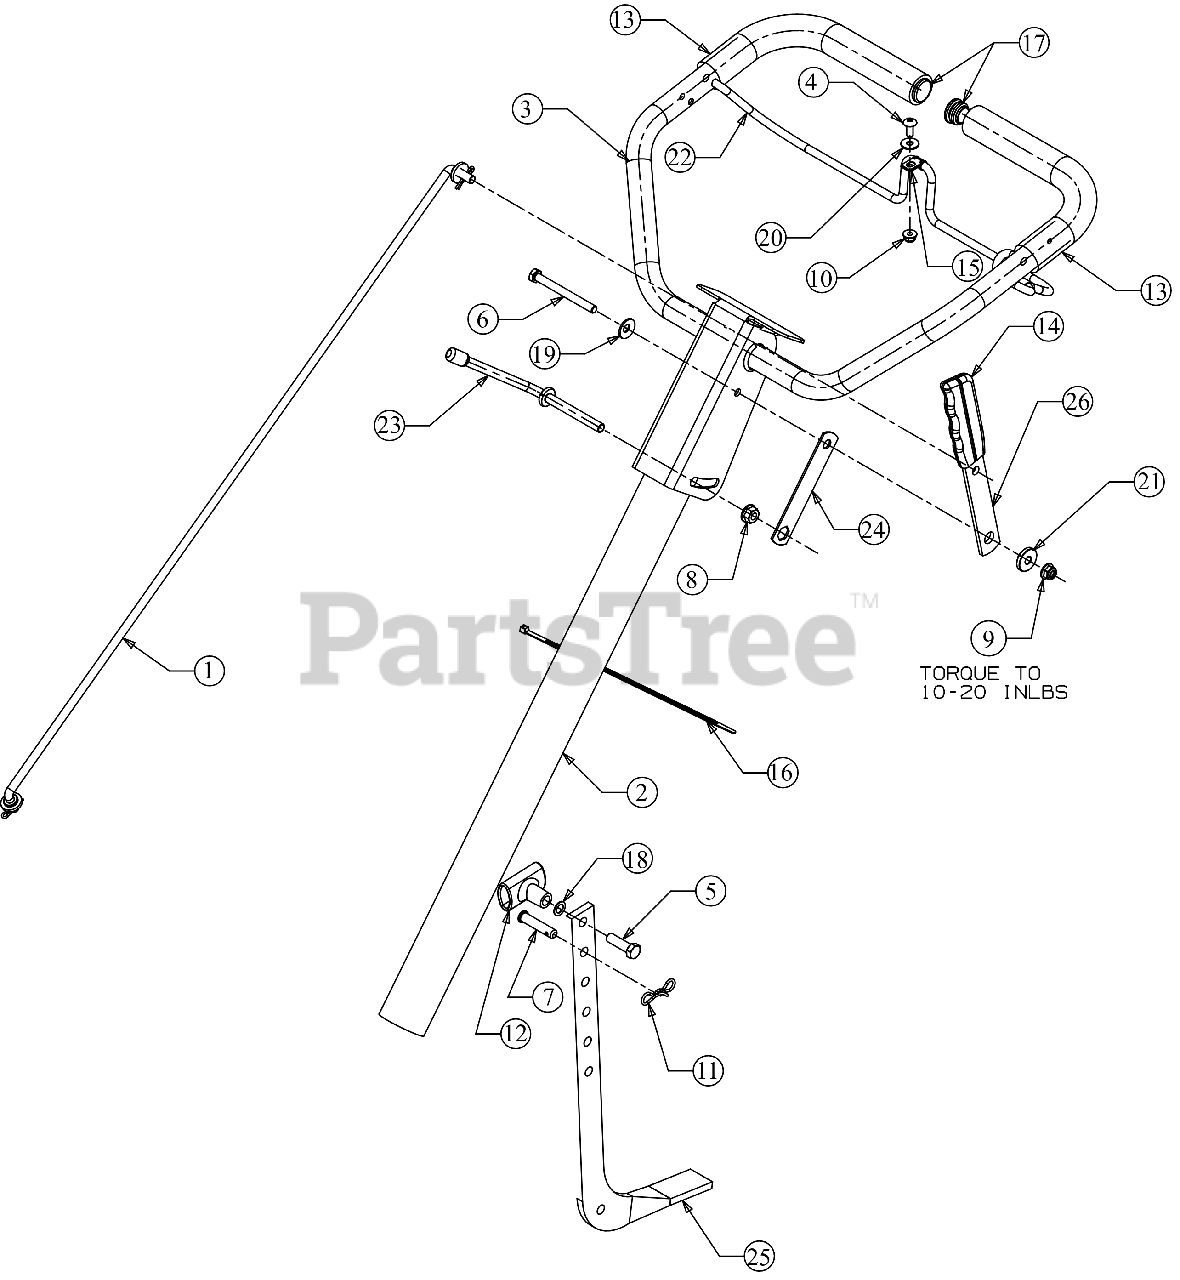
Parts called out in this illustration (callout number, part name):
1	SHIFT ROD
4	SCREW 1/4-20 X .625
5	SCREW 3/8-16 X 1.25 GR5
6	SCREW 5/16-18 X 3.25 GR5
7	CLEVIS PIN .375 X .1.75
8	FLANGE HEX NUT
9	FLANGE LOCK NUT 5/16-18
10	FLANGE LOCK NUT
11	PIN:COTTER
12	THROTTLE KNOB
13	FOAM GRIP .970 X 11.0
15	MOUNTING CLAMP
16	CABLE TIE
17	END PLUG
18	FLAT WASHER
19	BELL WASHER .337 X.867 X .057
20	FLAT WASHER
21	SHOULDER SPACER
22	CLUTCH BAIL
23	CRANK
24	RETAINER BRACKET
25	DEPTH BAR ASSEMBLY
